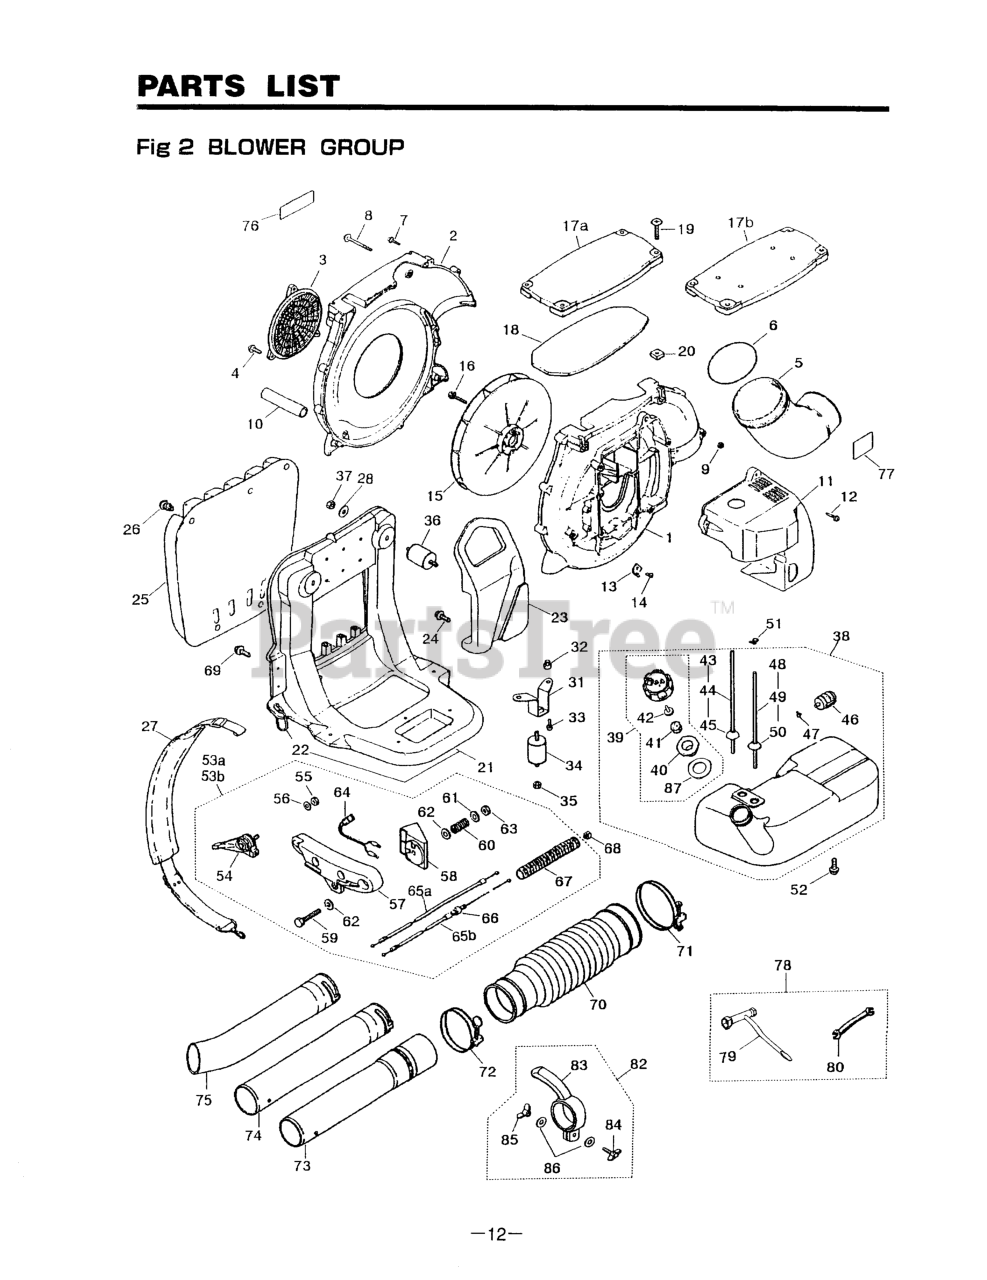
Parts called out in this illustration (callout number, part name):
1	CASE, VOLUTE
2	COVER, VOLUTE
3	NET, GUARD (RPLS-12222)
6	O-RING
7	SCREW
9	NUT (B)
11	COVER, ENGINE (RPLS-11210)
12	SCREW
15	FAN (REPLACES 3490-12110)
16	BOLT (RPLS 3405-12211)
17B	COVER (RPLS -13110)
18	COVER, PACKING
19	SCREW
20	NUT
22	RING (USE -21121)
23	HANGER (RPLS -21210)
25	PAD (RPLS -21310)
26	CLIP (RPLS 3490-21320)
28	WASHER, FLAT
31	BRACKET (RPLS -22510)
32	WASHER
33	SCREW, M5X20 (RPLS.1400-75510)
34	MOUNT (A) (RPLS 3490-22110)
35	NUT, M6 X 5
36	MOUNT (B) (RPLS 3405-22120)
37	NUT, M6 X 5
38	TANK ASSY (RPLS -23005)
39	CAP ASSY (RPLS -23202)
40	INNER CAP
43	PIPE (RPLS 3490-23410)
44	PIPE (USE 1696-85400)
45	GROMMET
46	FILTER ASSY
47	CLIP (REPLACES 2841-31280)
48	PIPE ASSEMBLY
49	PIPE (USE 1620-81710)
50	GROMMET
51	CLIP
52	SCREW, M5 x 12
53B	LEVER (EB441)
54	LEVER, THROTTLE
55	NUT (B)
56	WASHER, M5x.8(RPLS 01624-20508
58	BRACKET
59	BOLT
60	SPRING
61	WASHER
62	WASHER, FLAT
63	NUT, M6 X 5
64	SWITCH, STOP
65B	CABLE COMP,THROTTLE EB441
67	TUBE (USE 5548-73310)
68	NUT, M6 X 5
69	BOLT
70	HOSE, FLEXIBLE
71	2756-51510 (RPLS. 07280-09832)
73	JOINT, SWIVEL
74	PIPE, EXTENSION
75	PIPE, BENT
78	TOOL SET
80	SPANNER, 8 X 10 (RPLS 2540- )
82	BLOWER ASSIST HANDLE
83	EBH100
84	BOLT, WING
85	NUT, WING
86	WASHER
87	PACKING (RPLS -85321)
